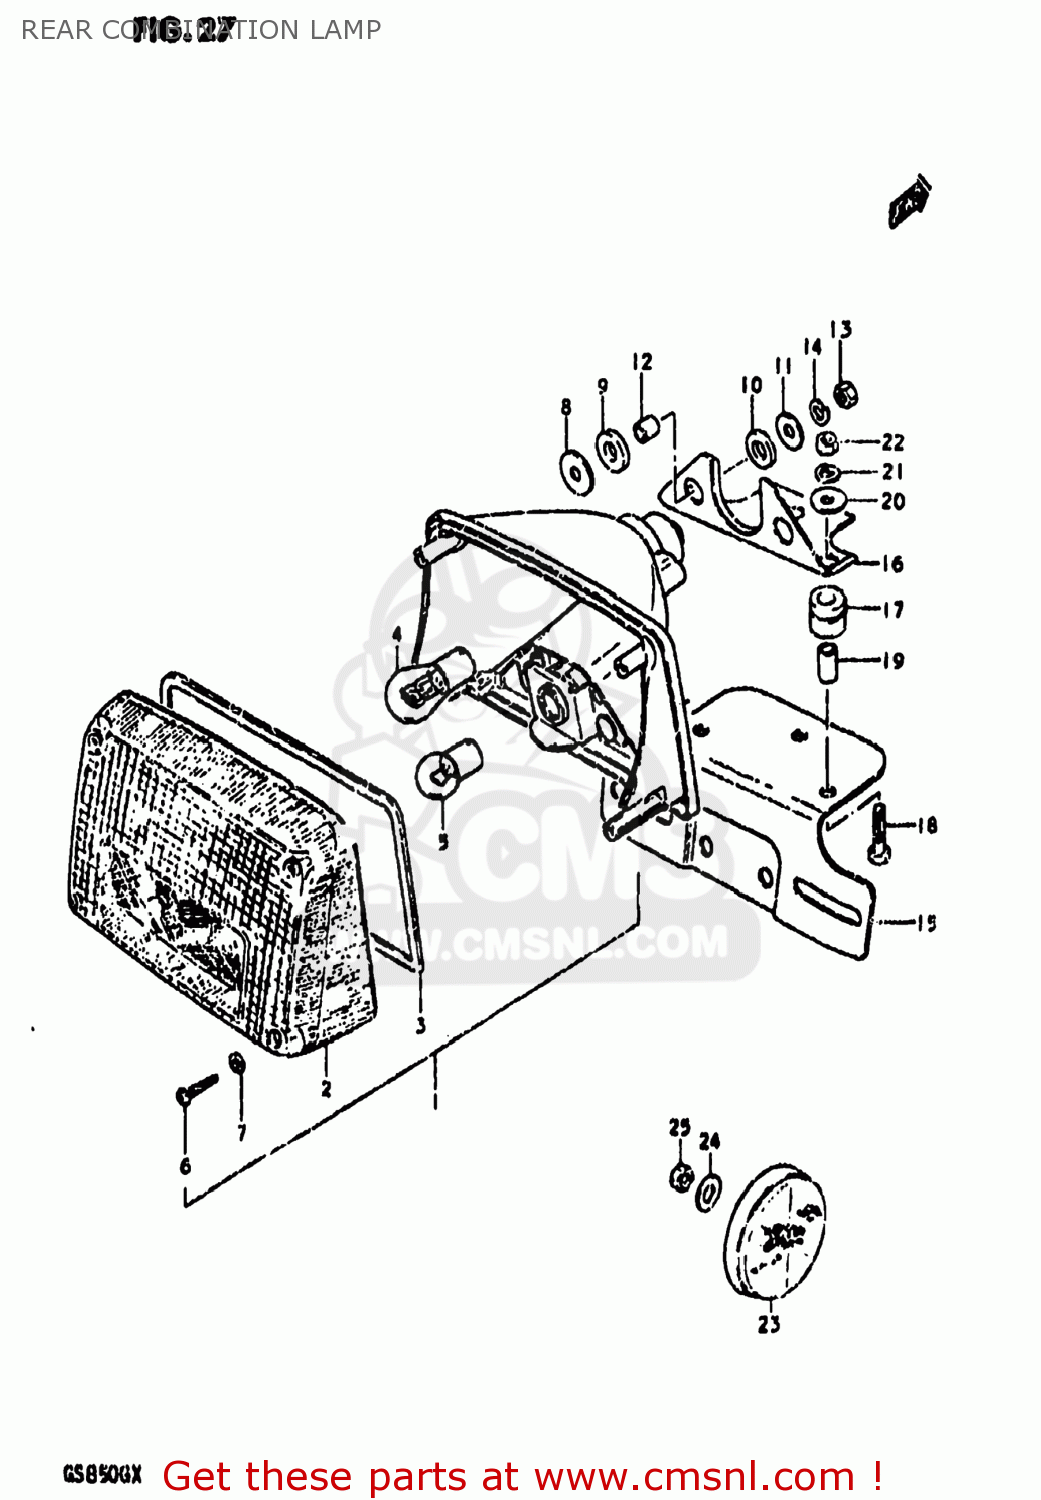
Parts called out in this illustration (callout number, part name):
1	LAMP ASSEMBLY,REAR COMBINATION
2	LENS
3	GASKET (NAS)
4	BULB(12V23W)
5	BULB
6	BOLT
7	GASKET (NAS)
8	WASHER
9	CUSHION
10	CUSHION
11	WASHER(6,5X22X1.6)
12	SPACER(6.1X9X7.5)
13	NUT
14	LOCK WASHER
15	PLATE,REAR LICENSE
16	BRACKET,LICENSE PLATE
17	CUSHION, BRACKET
18	BOLT
19	SPACER (6.4X9X15.5)
20	WASHER (8.7X22X2)
21	LOCK WASHER
22	NUT
23	REFLEX REFLECTOR,RR
24	WASHER
25	NUT
